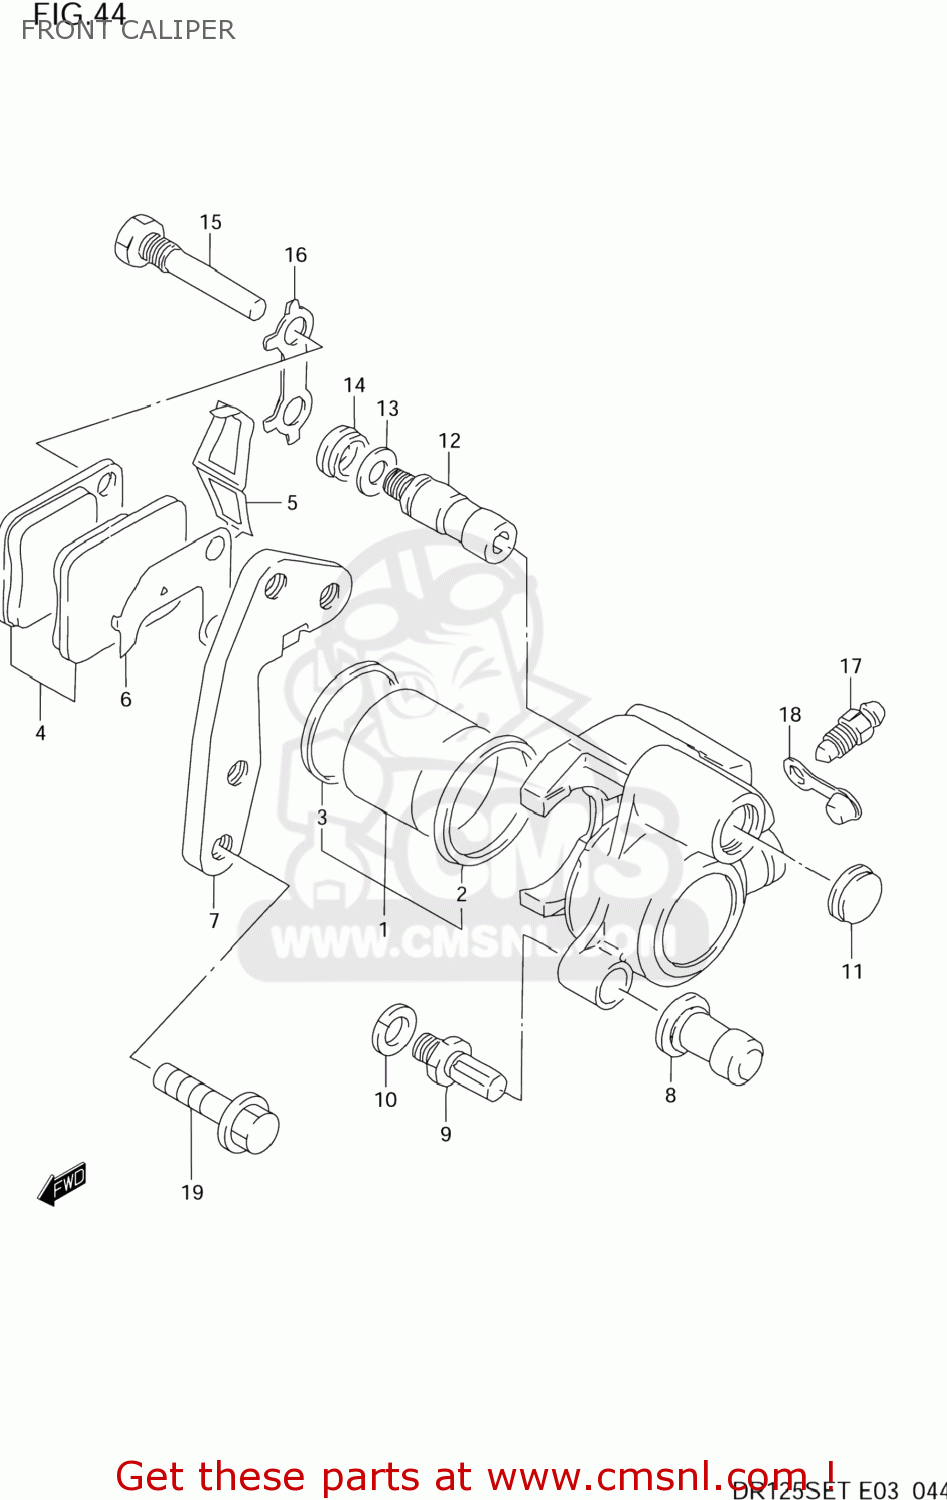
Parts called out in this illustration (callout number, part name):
1	PISTON SET,CALIPERS
2	SEAL,PISTON
3	BOOT,PISTON
4	PAD SET (NAS)
5	SPRING,PAD
6	SHIM
7	BRACKET
8	BOOT
9	BOLT,PIN
10	WASHER,WAVE
11	DUST SEAL
12	PIN,SLIDE
13	SPRING,FRICTION
14	BOOT,PIN
15	PIN,HANGER
16	WASHER
17	BLEEDER
18	CAP,BLEEDER
19	BOLT(8X30)
